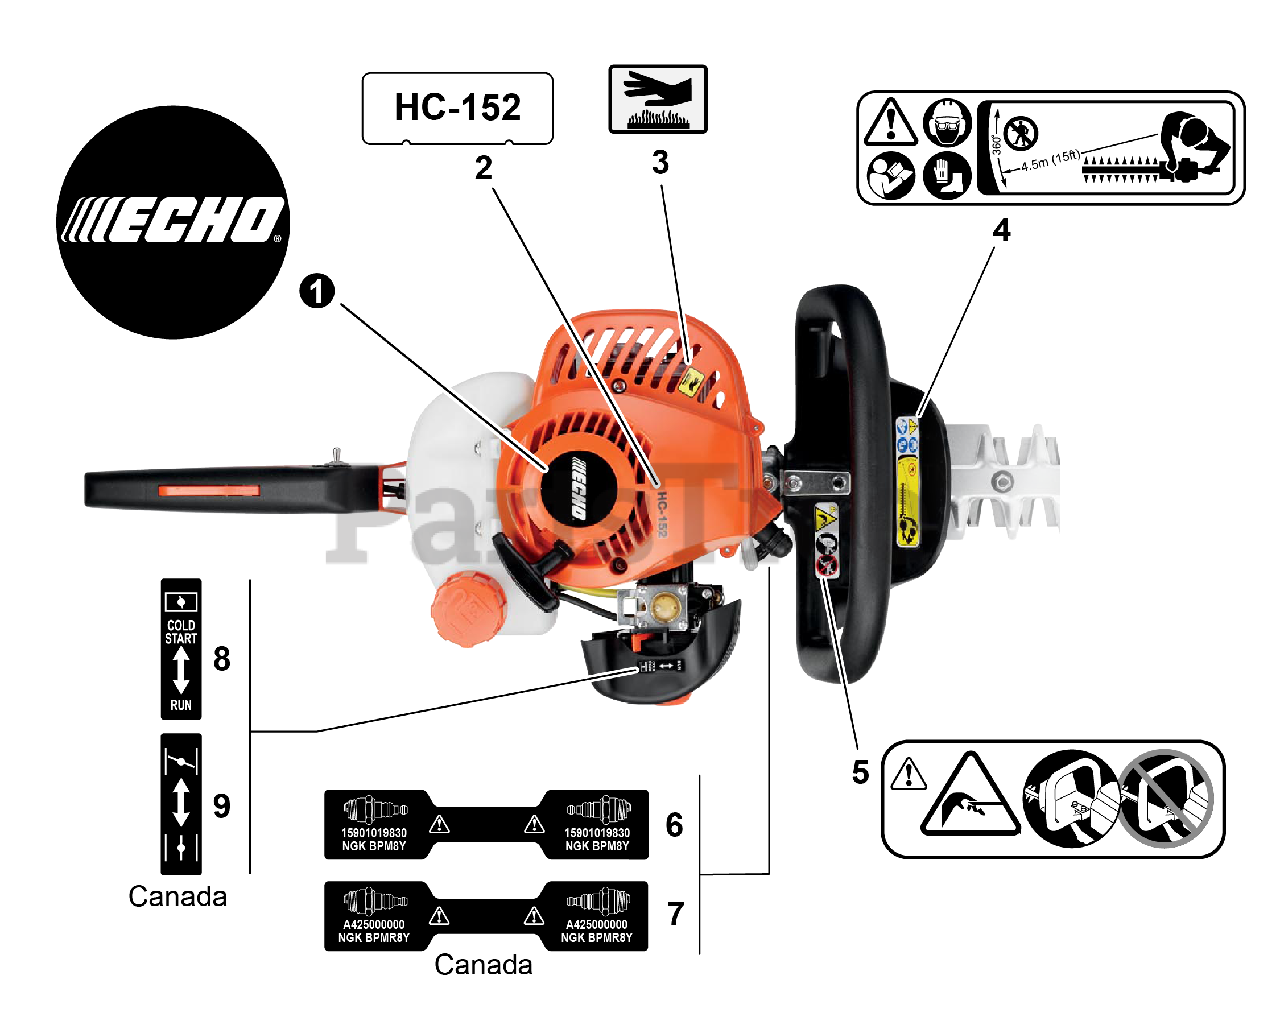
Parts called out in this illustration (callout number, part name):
1	LABEL, ECHO
2	LABEL, MODEL HC-152
3	LABEL, CAUTION - HOT
4	LABEL, CAUTION - ISO
5	LABEL, CAUTION
6	LABEL, SPARK PLUG - BPM8Y
7	LABEL, SPARK PLUG - BPMR8Y
8	LABEL, CHOKE
9	LABEL, CHOKE
